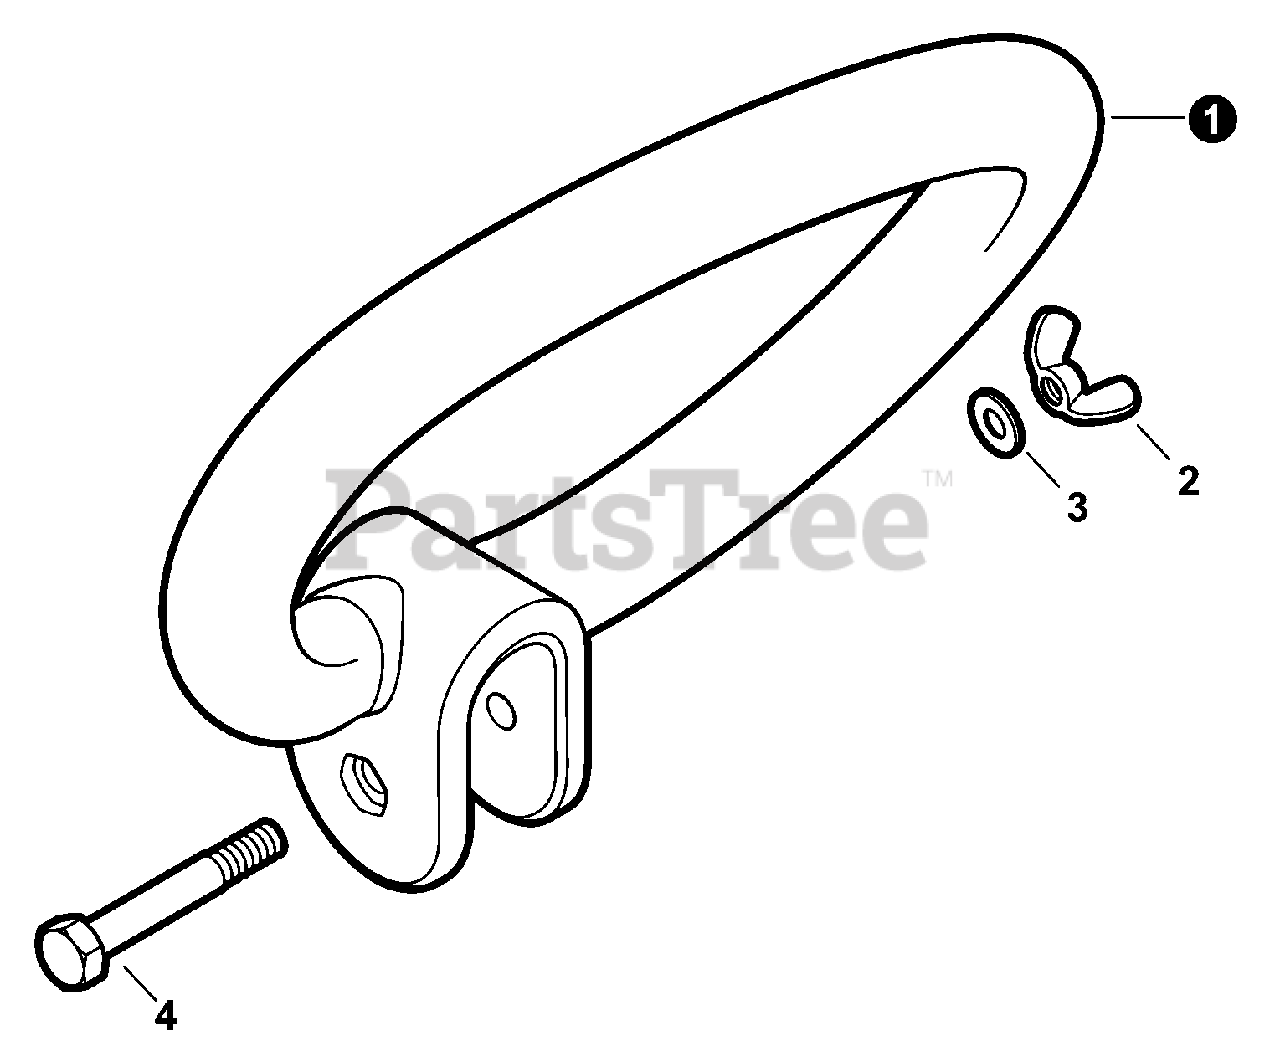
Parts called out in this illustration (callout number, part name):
1	HANDLE, SUPPORT
2	NUT, WING 1/4"-20
3	WASHER, 1/4"
4	BOLT 1/4"-20×2"
